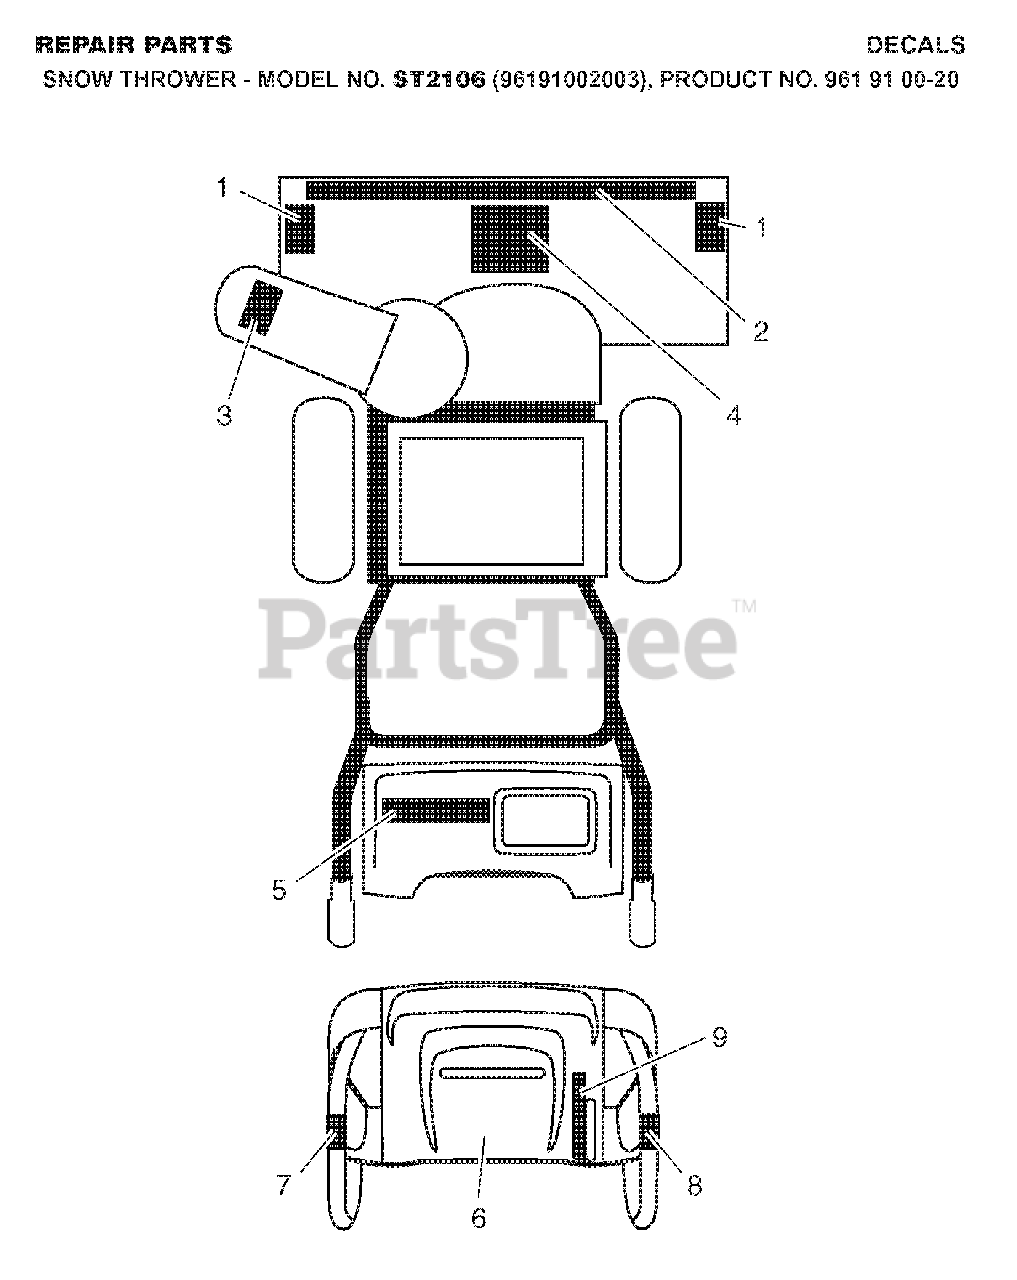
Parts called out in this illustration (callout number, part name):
1	DECAL.AUGER.SAFETY.
3	DECAL.CHUTE.SAFETY.
4	DECAL.AUGER."
6	DECAL.CONSOLE.INSTRUCTION
